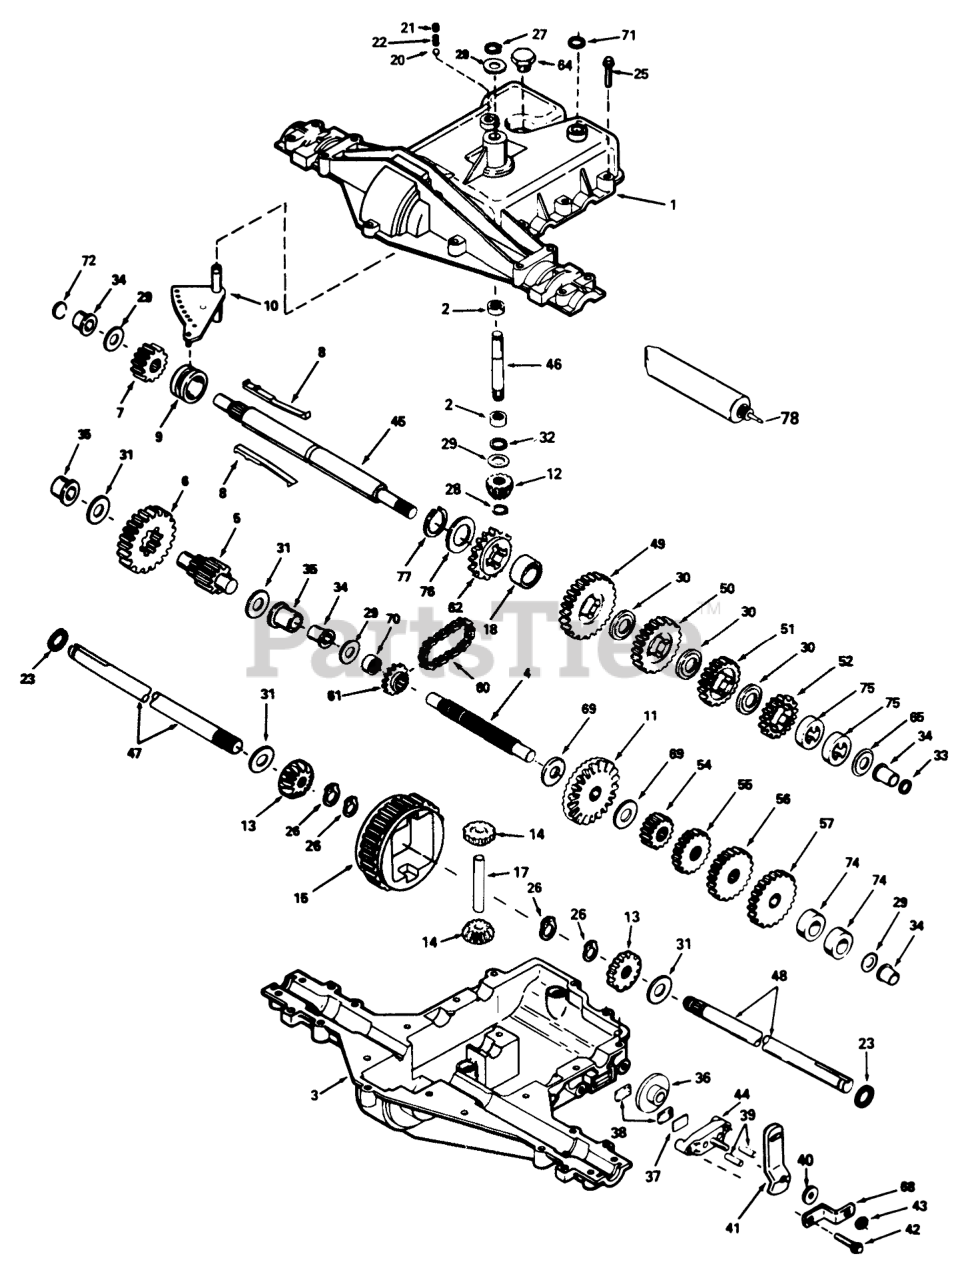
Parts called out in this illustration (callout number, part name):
1	PEDAL BRAKE R
2	SHAFT PEDAL
3	CLAMP
4	SPACER
5	WASHER-WAVE
6	Lock Rod
8	ARM-IDLER R
9	BUSHING
10	WASHER-BEARING
12	ROD-CLUTCH/BRAKE B
13	PULLEY IDLER
14	GUIDE-BELT
15	SPACER
17	SPRING - BRAKE
18	SPRING - CLUTCH
19	NUT-LOCK, NI
20	SCREW-CARR
21	PIN-COTTER
22	Washer
23	PIN-COTTER
24	WASHER-PLAIN
25	BOLT-CARR
26	NUT-LOCK, NI
27	SCREW-CARR
28	WASHER-FLAT
29	EXTENSION-SPRING
